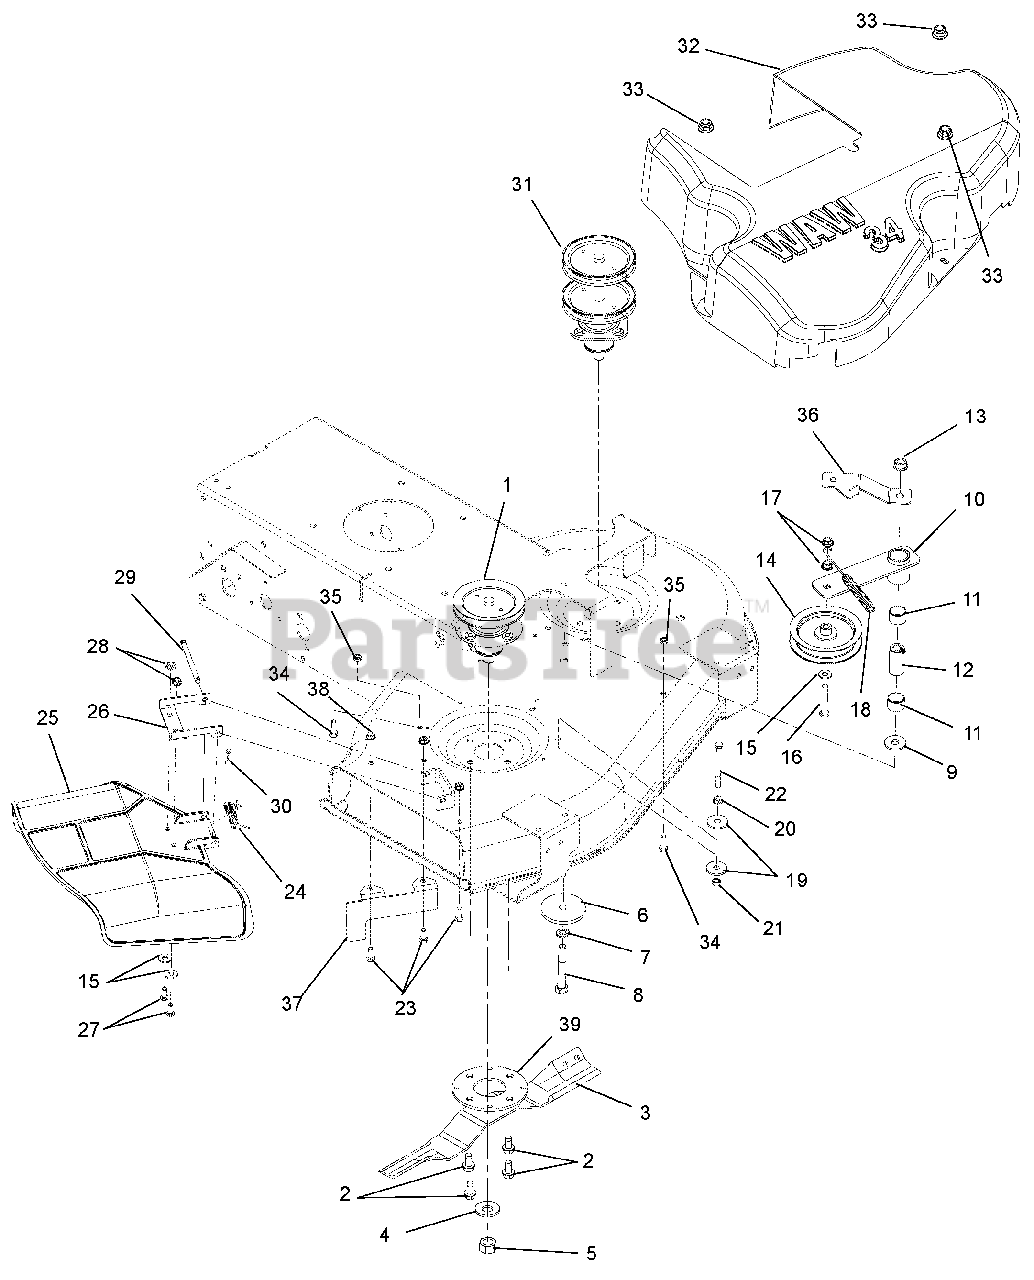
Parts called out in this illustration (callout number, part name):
1	Kit, Deck Spindle Assembly (34/50)
2	Screw, Tapping .38-16 x .75 Hex Washer Head (Torque = 324 – 420 lbf-in (36.61 – 47.45 Nm))
3	Blade-17.2" x .156
4	Washer, Bellville .63 x 1.62 x .14
5	Nut, Hex .62-18 (Torque = 100-120 lbf-ft (135.6-162.7 Nm))
6	Washer, Flat .531 x 3.00 x .25
7	Washer, Locking .50 x .125
8	Bolt, Hex .50-13 x 3.50
9	Washer, Flat Steel .511 x 1.44 x .125
10	Arm, WAW Deck Idler
11	Bearing 1.00 x 1.12 x .75
12	Bushing, Spacer .505/.500 x .999/.996 x 2.05/2.03
13	Nut, Locking Top Flange .50-13
14	Idler, Flat .38 x 4.00 x 1.06
15	Washer, Flat Steel .38 x .875 x .083
16	Bolt, Hex .38-16 x 2.25
17	Nut, Locking Flange .375-16
18	Spring, Engine-Transmission
19	Washer, Flat Steel .406 x 1.375 x .135
20	Nut, Spin Lock Flange .312-18
21	Nut, Locking Center .31-18
22	Bolt, Hex .31-18 x 3.50
23	Bolt, Hex .31-18 x .75
24	Spring, Torsion
25	Chute, Side Discharge
26	Reinforcement, Chute
27	Screw, Socket Head .31-18 x .75 Button Head
28	Nut, Locking Top Flange .31-18
29	Pin, .3125 x 3.88
30	Pin, Internal Hair .08 x .18 x 1.18
31	Kit, WAW Deck Input Pulley
32	Cover, Belt
33	Nut, .31-18 Nyloc Flange
34	Bolt, Hex .31-18 x 1.00
35	Nut, Locking Center .31-18
36	Bracket, Idler Brace
37	Bracket, Baffle, Discharge 34"
38	Nut, Locking-Nylon-Flange .31-18
39	Plate, Reinforce, Spindle
